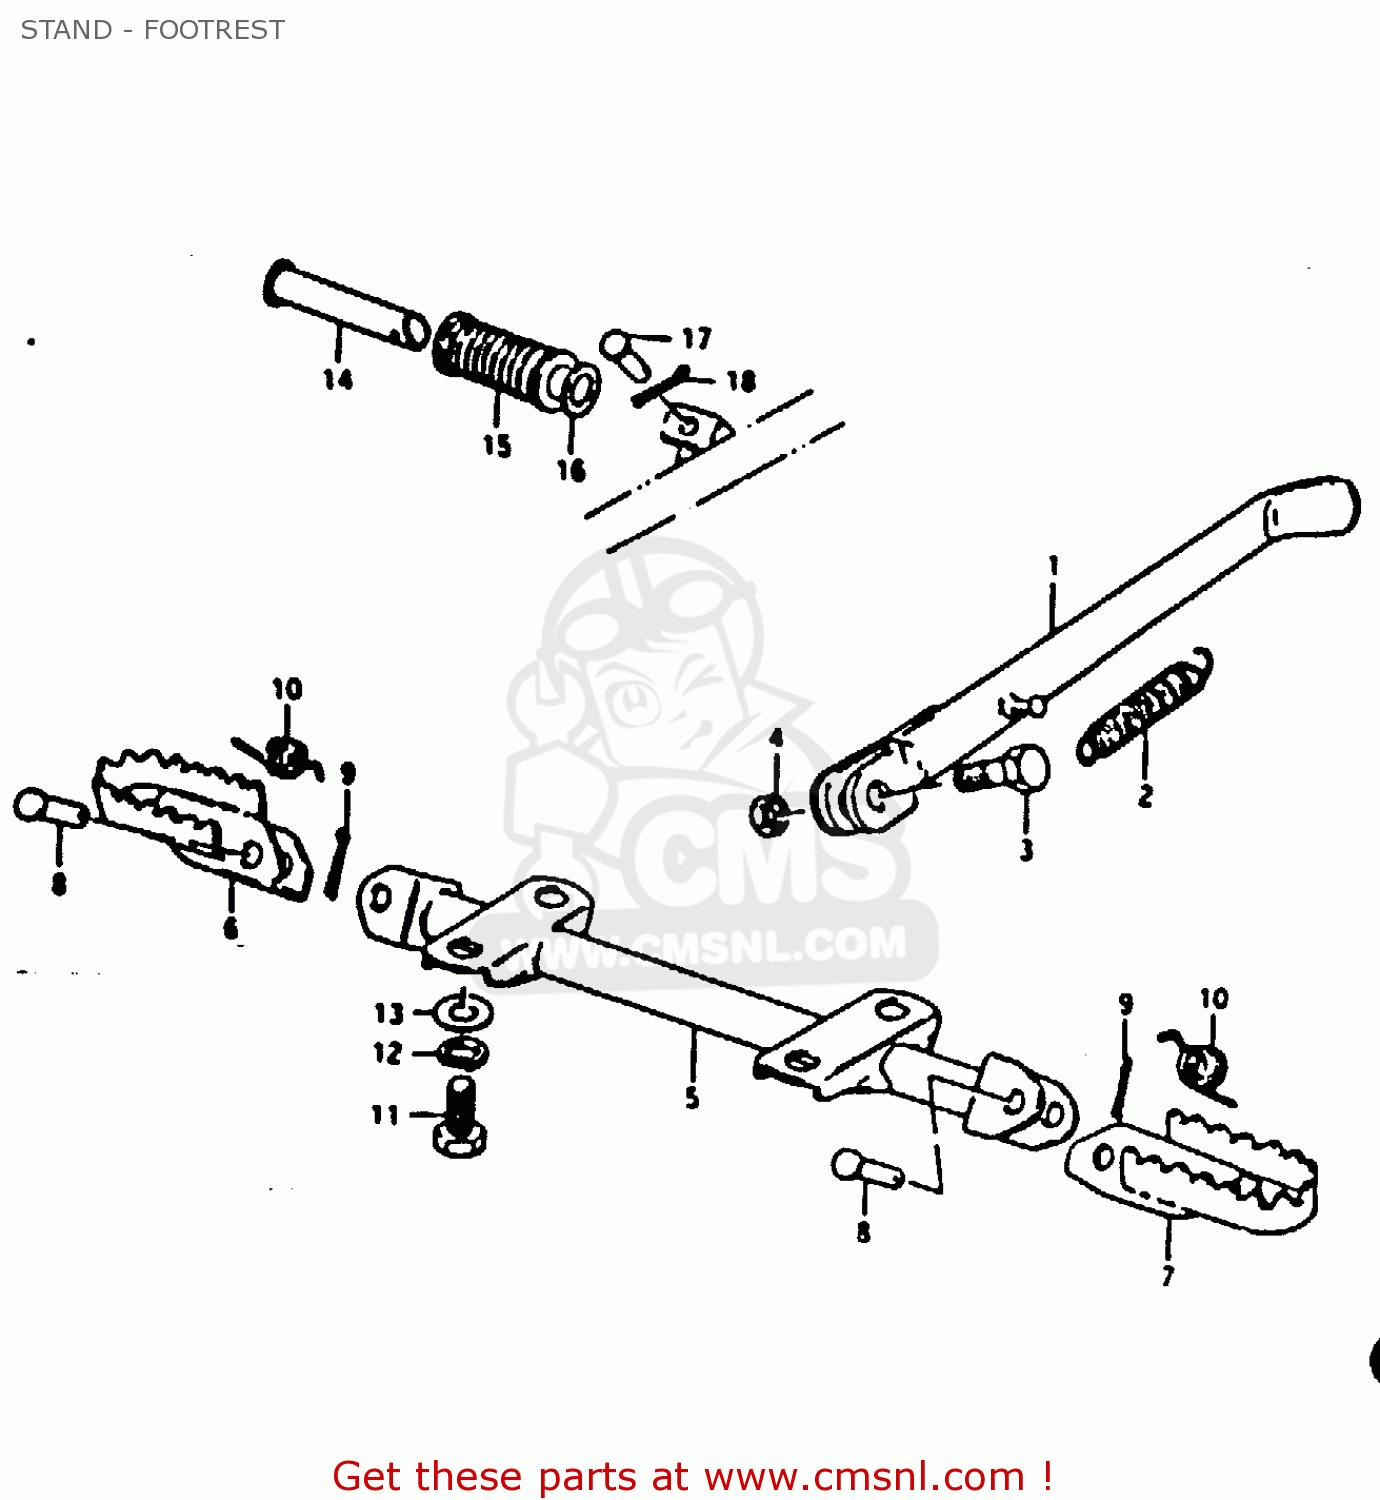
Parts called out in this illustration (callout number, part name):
1	STAND,SIDE
2	SPRING
3	BOLT(10X30)
4	NUT
5	BAR,FR FOOTREST
6	FOOTREST,FR,R
7	FOOTREST,FR,L
8	PIN
9	PIN 20X20
10	SPRING
11	BOLT
12	LOCK WASHER
13	WASHER
14	BAR,FOOTREST RUBBER
15	RUBBER,PILLION FOOTREST
16	WASHER (19.5X32X2)
17	PIN
18	PIN 20X20
